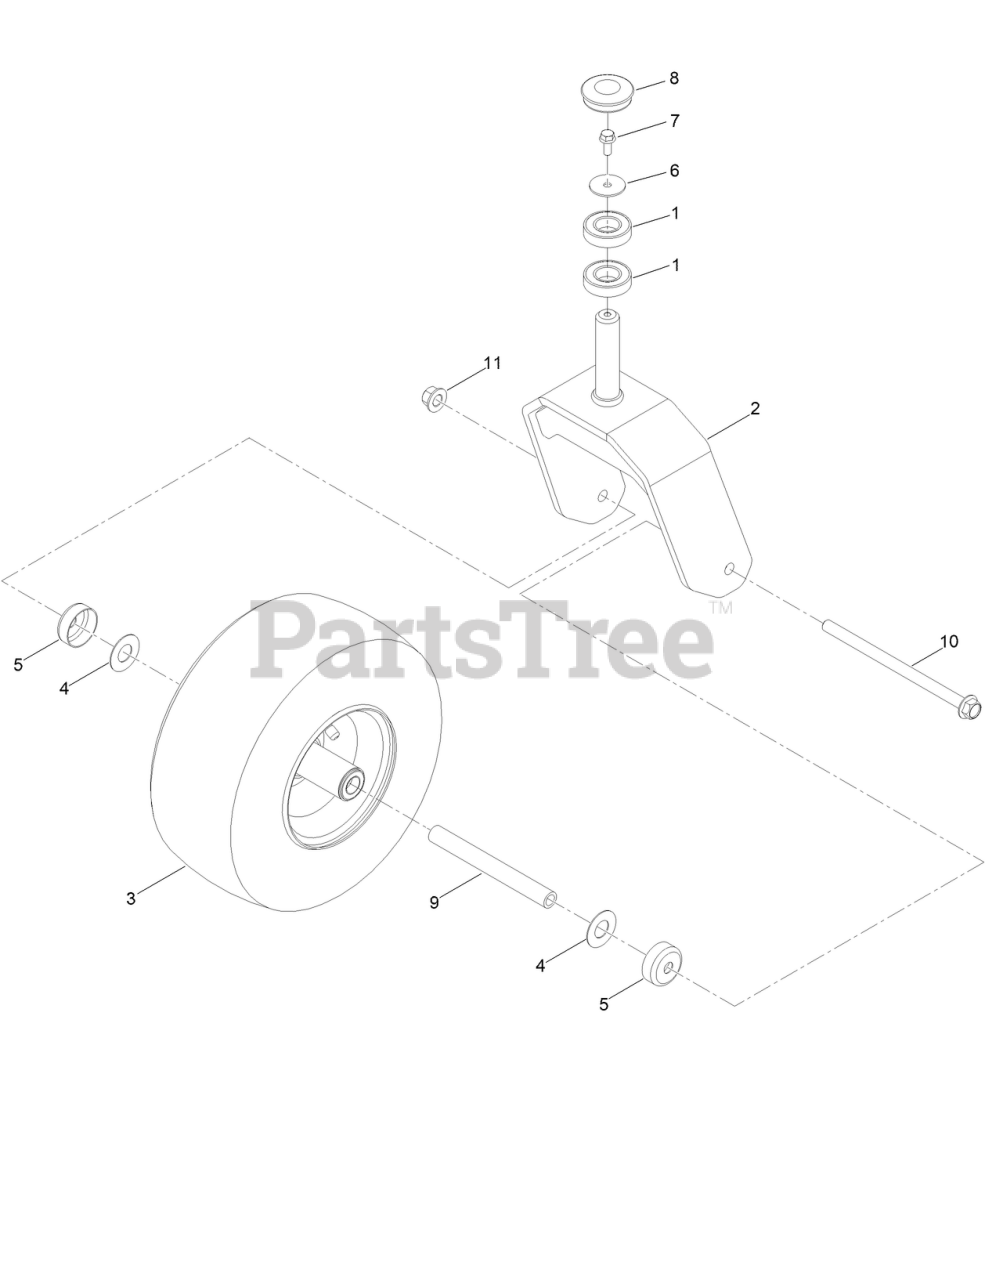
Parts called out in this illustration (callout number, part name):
1	BEARING-BALL
2	CASTOR FORK [GRAY]
3	TIRE AND WHEEL ASM
4	WASHER
5	GUARD-SEAL
6	WASHER-FLAT
7	SCREW-HHF
8	CAP,GREASE
9	SPANNER-WHEEL
10	SCREW-HHF
11	NUT-HF
